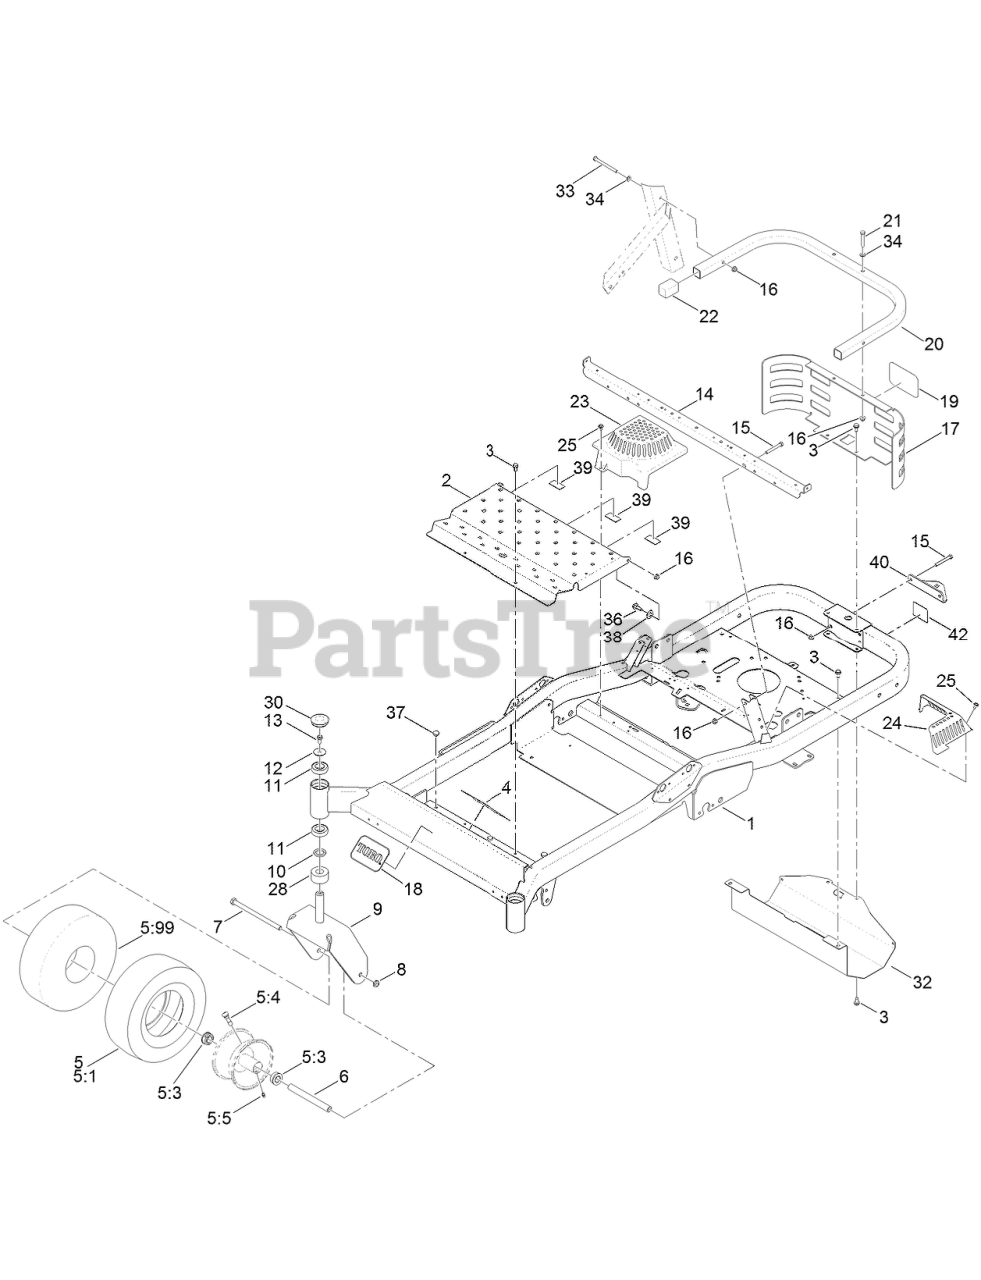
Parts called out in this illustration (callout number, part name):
1	FRAME ASM
2	PAN-FLOOR
3	SCREW-HWHTF
4	DECAL-DANGER
5	TIRE AND WHEEL ASM
5:1	TIRE-13 INCH SMOOTH
5:3	BUSHING-FLANGE
5:4	STEM-VALVE
5:5	FITTING-GREASE
5:99	TUBE-INNER
6	SPANNER
7	SCREW-HH
8	NUT-LOCK, NI
9	FORK-CASTER
10	WASHER-THRUST
11	BEARING-BALL
12	WASHER-FLAT
13	SCREW-HHF
14	SUPPORT-SEAT
15	SCREW-HH
16	NUT-HF, NI
17	GUARD-REAR
18	DECAL
20	TUBE-GUARD
21	SCREW-HH
23	COVER-FAN, RH
24	COVER-FAN, LH
25	SCREW-HHFTF
28	SPACER-CASTER
30	CAP-GREASE
32	SHIELD-HEAT
33	SCREW-HH
34	WASHER-PLAIN
36	SCREW-SHOULDER
37	BUMPER
38	WASHER-TEFLON
39	PAD-RUBBER
40	BRACKET-HITCH
